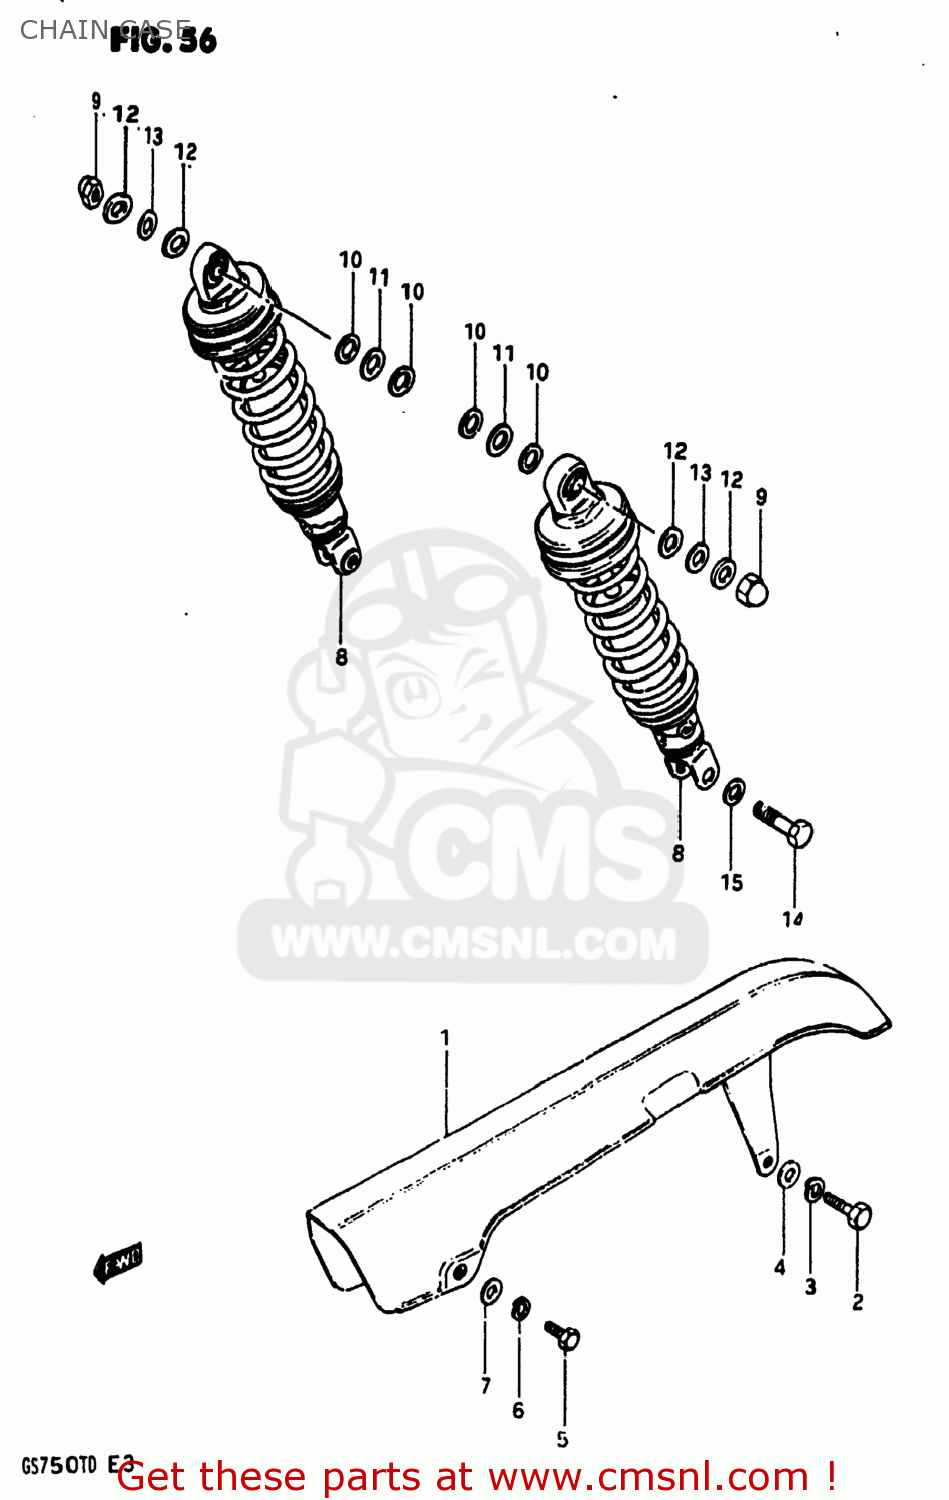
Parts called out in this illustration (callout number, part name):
1	CASE,CHAIN
2	BOLT
3	LOCK WASHER
4	WASHER
5	BOLT
6	LOCK WASHER
7	WASHER
8	ABSORBER ASSEMBLY,REAR SHOCK
9	NUT, LOWER LH
10	WASHER
11	WASHER (12.5X24X3.2)
12	WASHER
13	WASHER(10.5X24X3.2)
14	BOLT(10X36)
15	WASHER
